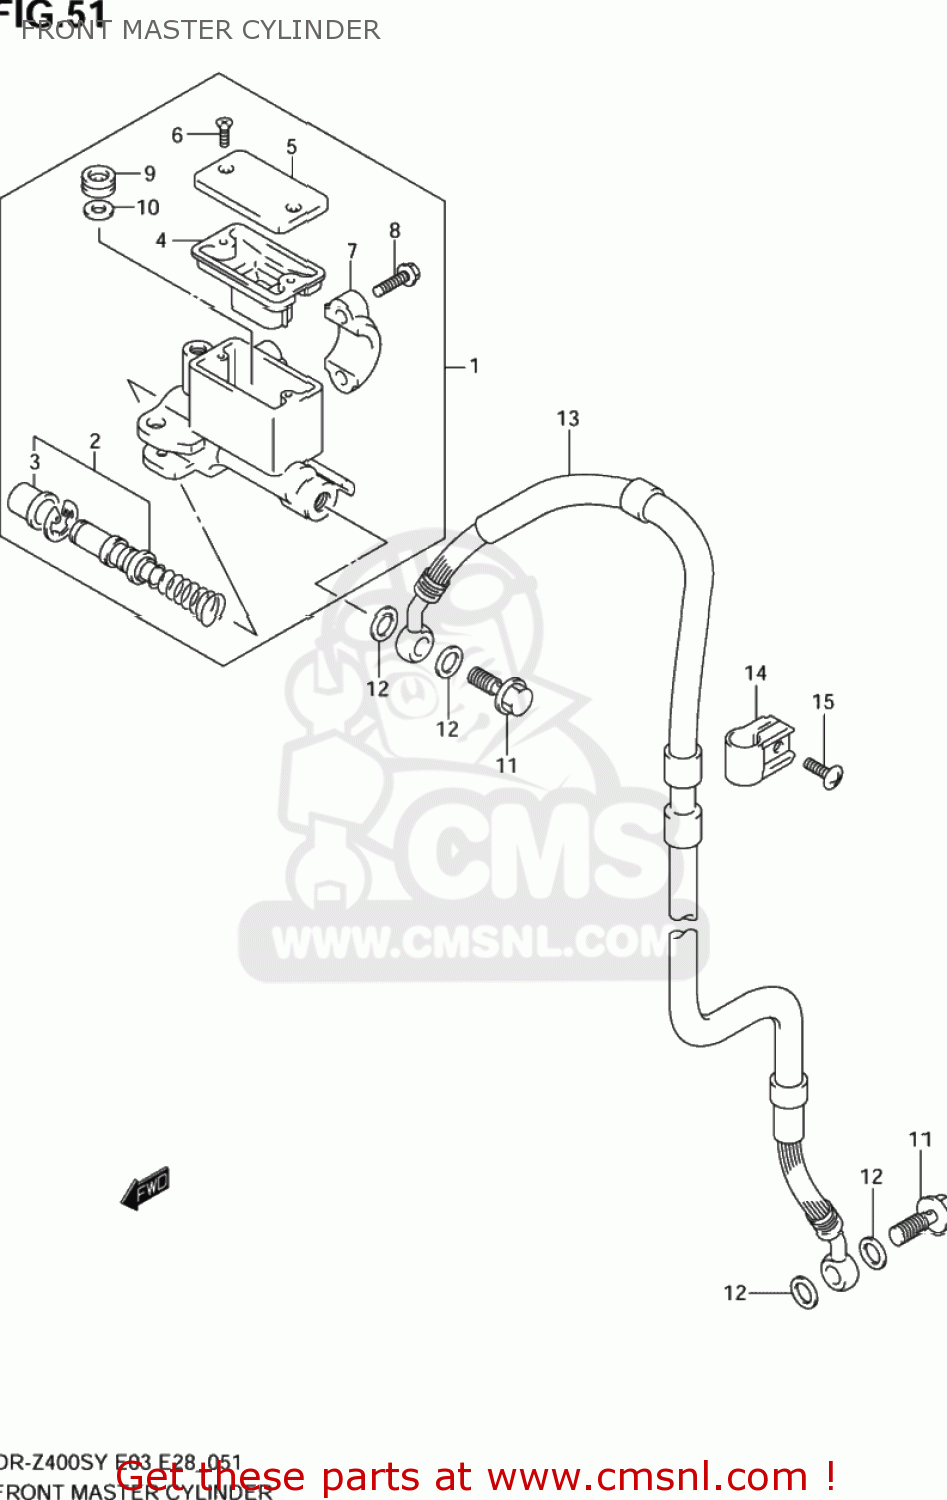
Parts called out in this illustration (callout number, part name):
1	CYLINDER ASSY,FR MASTER
2	PISTON/CUP SET
3	BOOT
4	DIAPHRAGM
5	CAP
6	SCREW
7	HOLDER
8	BOLT
9	SEPARATOR
10	RING
11	BOLT UNION
12	WASHER(10X15X1.5)
13	HOSE COMP,FRONT BRAKE
14	CLAMP,BRAKE HOSE
15	SCREW
